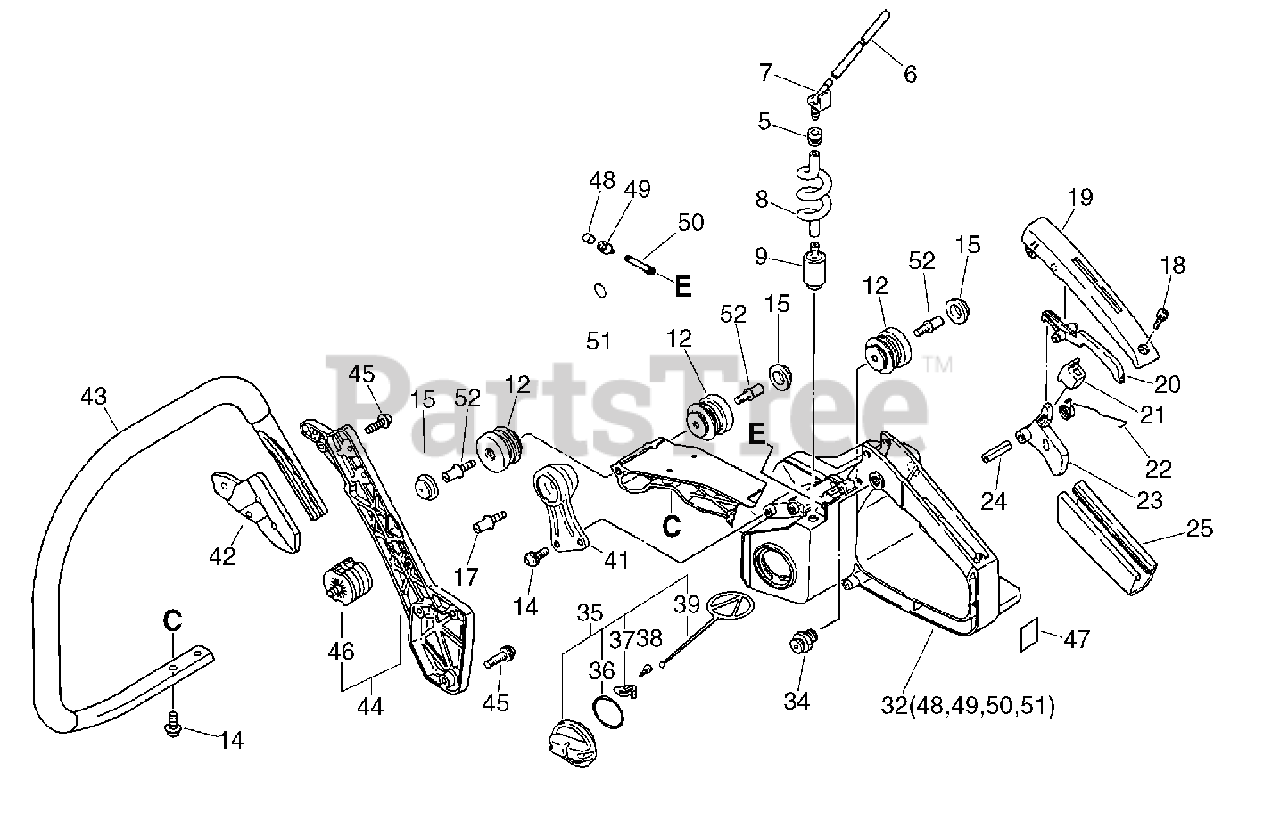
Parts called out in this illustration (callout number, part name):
5	GROMMET
6	PIPE, FUEL - 3×6×100
7	CONNECTOR, PIPE
8	PIPE, FUEL
9	FILTER, FUEL
12	CUSHION
14	BOLT 5×14
15	CAP, CUSHION
18	SCREW 4×14
19	COVER, HANDLE
20	CONTROL, THROTTLE
21	CUSHION, THROTTLE
22	SPRING, THROTTLE RETURN
23	TRIGGER, THROTTLE - BLACK
24	PIN, SPRING Ø5×25 MM
32	HANDLE - REAR
34	LATCH, THROTTLE
35	CAP ASSY, FUEL
36	O-RING 29
37	RETAINER, CONNECTOR
38	SCREW, TAPPING 3×8
39	CONNECTOR, CAP L= 60 MM
42	BRACKET, FRONT HANDLE
43	HANDLE, FRONT
44	SUPPORT KIT, FRONT HANDLE
45	SCREW 5×20
47	LABEL, STOP
48	VENT ASSY
49	HOLDER, VENT
50	PIPE, VENT
